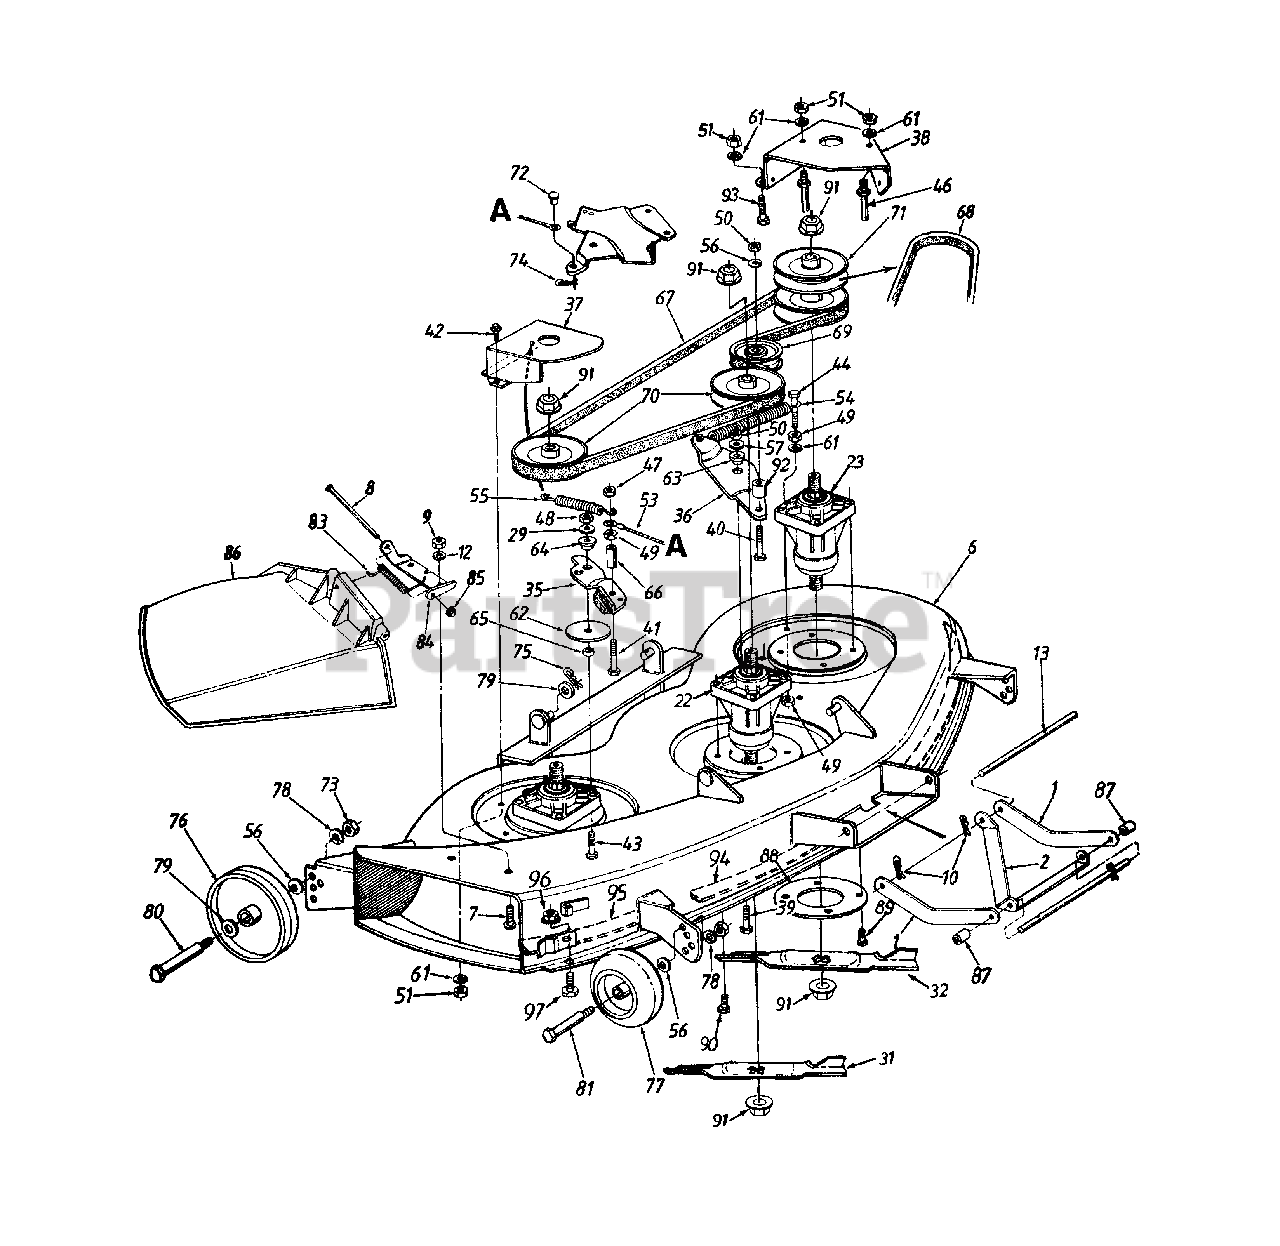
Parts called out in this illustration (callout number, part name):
8	Hinge Pin
9	Hex Nut 1/4-20 Thd. (Gr. 5)
10	Hairpin Clip
12	Bell-Wash. 1/4" I.D.
13	Deck Connecting Rod
22	Spindle Ass'y. (R.H. & Center)
23	Spindle Ass'y. (L.H.)
29	Lock Wash. 5/16" I.D.
31	Blade 14.88" Lg. (Middle)
32	Blade 16.28" Lg. (R.H. & L.H.)
35	Deck Brake Brkt. Ass'y.
36	Idler Bracket
39	Hex Bolt 3/8-24 x 1.0" Lg.
40	Hex Bolt 3/8-24 x 2" Lg.
41	Hex Bolt 1/4-28 x 1.75" Lg.
42	Hex Wash. Hd. Tap-Scr. 1/4-20 x .5" Lg.
43	Hex Bolt 5/16-24 x 1.5" Lg.(Grade 5)
44	Hex Bolt 1/4-28 x 1.5" Lg.
46	Belt Guard Pin 1/4" Dia.
47	Hex Cent. L-Nut 1/4-28 Thd.
48	Hex Nut 5/16-24 Thd.
49	Hex Nut 1/4-28 Thd.
50	Hex Nut 3/8-24 Thd.
51	Hex Nut 1/4-20 Thd. (Gr. 5)
53	Brake Cable Ass'y.
54	Extension Spring 6.17" Lg.
55	Extension Spring 3.97" Lg.
56	Bell-Wash..38" I.D. x .88" O.D.
57	Bell-Wash..39" I.D. x 1.13" O.D.
61	L-Wash. 1/4" I.D.
62	Fl-Wash. 5/16" I.D. x 3" O.D.
63	Shld. Spacer.625" I.D.
64	Shld. Spacer
65	Spacer .34" I.D.
66	Spacer .326" I.D.
67	V-Belt
68	V-Belt
69	Fl-ldler Pulley 3.5" O.D.
70	Pulley 5.0" Dia.
71	Double Pulley 5.0" Dia.
72	Clevis Pin 1/4" Dia. x .53" Lg.
73	Hex Nut 3/8-16 Thd.
74	Intern. Cotter Pin 5/16" Dia.
75	Intern. Cotter Pin 3/8 Dia.
76	Deck Wheel 5" Dia.
77	Deck Wheel w/Insert 5" Dia.
78	L-Wash. 3/8" I.D.
79	Fl-Wash..531" I.D.
80	Shoulder Bolt .498" Dia. x 1.64" Lg.
81	Shoulder Bolt
83	Torsion Spring
84	Hinge Mtg. Brkt.
85	Push Nut
86	Chute Ass'y. Comp.
87	Spacer 5/8" I.D. x 7/8" O.D.
90	Hex Wash. Hd. Scr. 5/16-18 x .75" Lg.
91	Hex Flange Nut 5/8-18 Thd.
92	Spacer .38" I.D.
93	Hex Bolt 1/4-20 x .5" Lg.
96	Hex Sems Nut 1/4-20 Thd.
97	Carriage Bolt 1/4-20 x .5" Lg.
